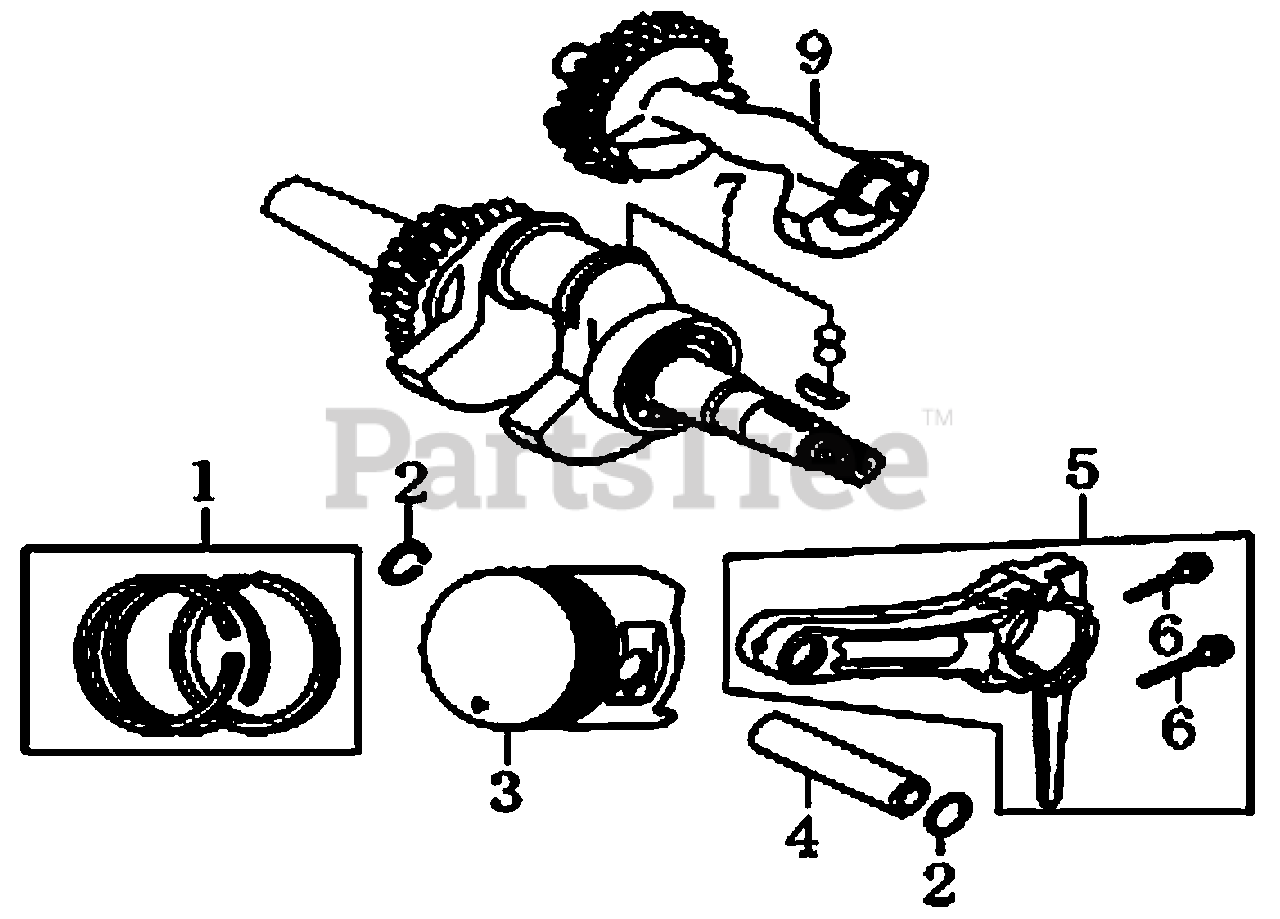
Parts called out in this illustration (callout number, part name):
1	RING SET,PISTON
2	CLIP,PISTON PIN
4	PIN,PISTON
5	CONNECTING ROD ASSY
6	BOLT,CONNECTING ROD
7	CRANKSHAFT ASSY
8	KEY,SPECIAL WOODRUFF
9	WEIGHT,BALANCER
